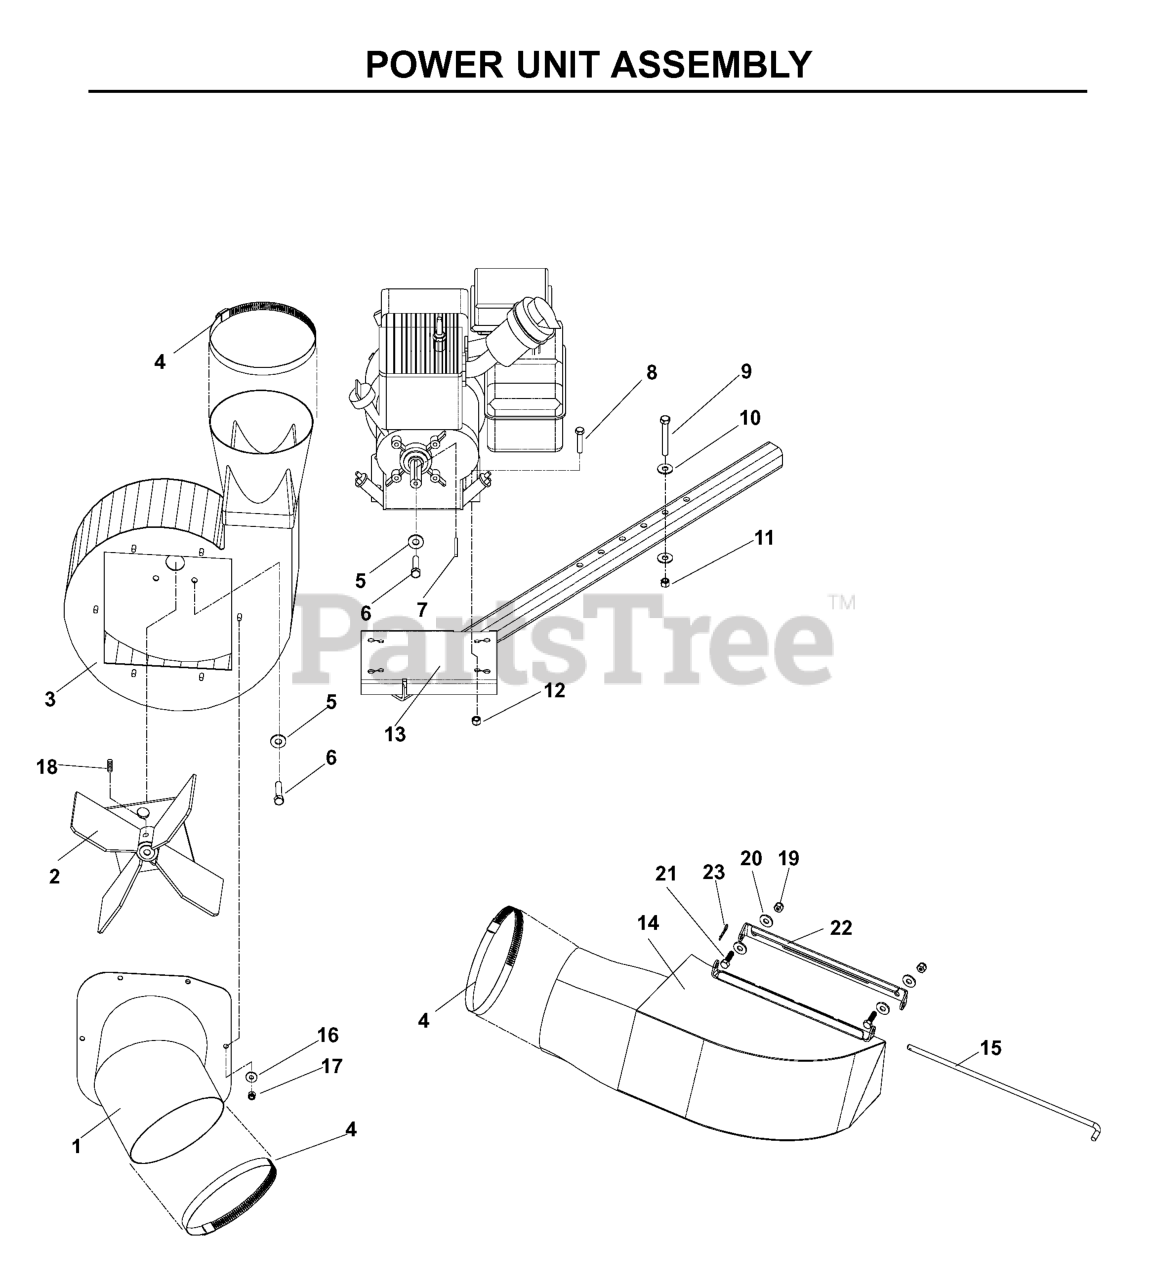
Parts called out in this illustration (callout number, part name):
1	BLOWER HOUSING INLET
3	BLOWER HOUSING
4	HOSE CLAMP
5	R/B 109600 WASH SPRING, 5/16
6	R/B 990233 BLT HEX 5/16-24X3/4
7	KEY SQUARE 3/16 X 3/16 X 1 3/4
8	Bolt, Hex, 5/16"-18 x 1-1/2"
9	HEX BOLT 3/8-16 X 2.5"
10	FLAT WASHER 3/8
11	NUT 3/8 NYLOC
12	HEX NUT - NYLON LOCK 5/16-18
13	ENGINE MOUNT
14	BOOT, GEN II
15	BOOT ROD - 14"
16	Washer, Flat, 1/4"
17	Nut, Hex, Nylon Lock, 1/4"-20
18	SCREW SET, 3/8-24 X 3/8
19	HEX NUT - NYLON LOCK 5/16-18
20	Washer, Flat, 5/16"
21	Bolt, Hex, 5/16"-18 x 1"
23	PIN, HAIR COTTER #13 5/64 X 1
